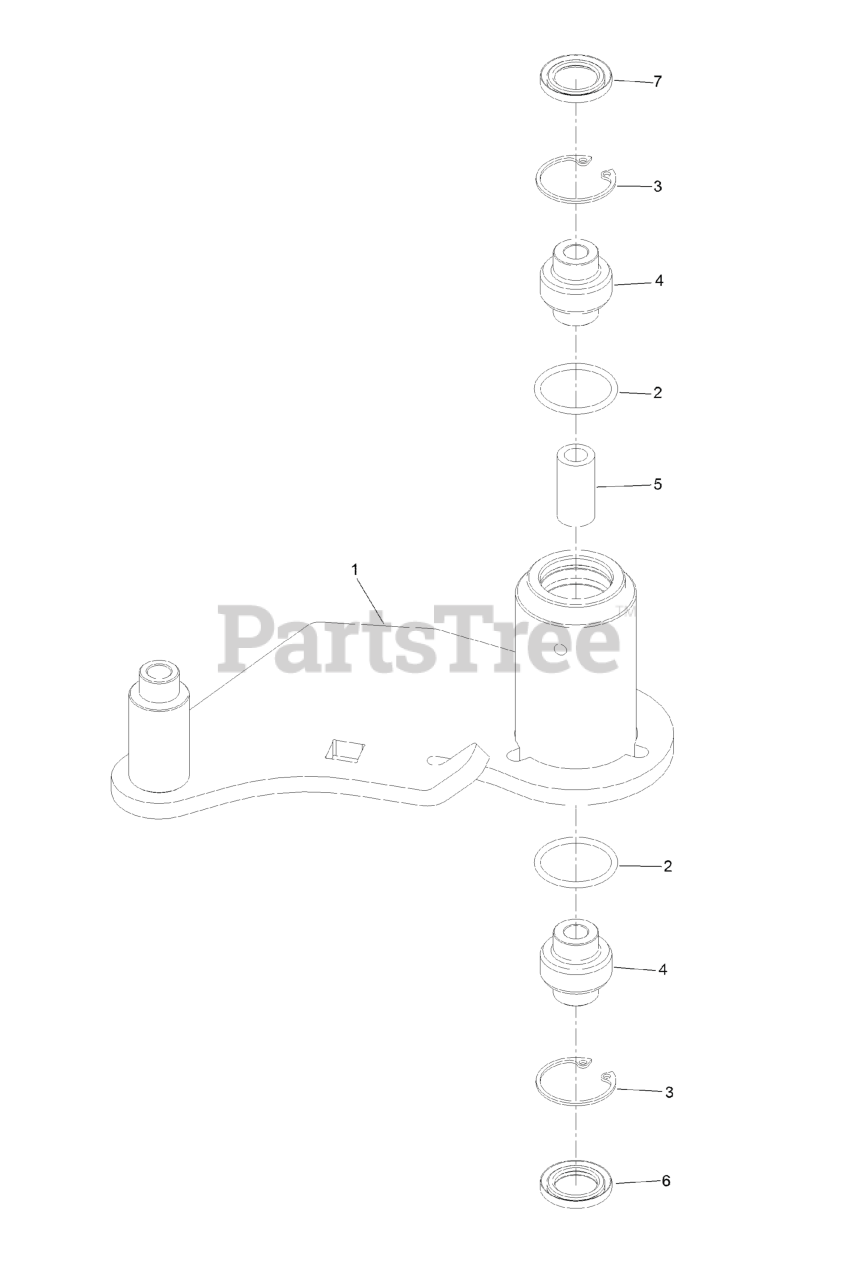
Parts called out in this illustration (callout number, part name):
1	Idler-Deck
3	RING-SNAP
4	BEARING-SPHERICAL
6	SEAL-LIP, DOUBLE
7	SEAL-LIP, SINGLE
